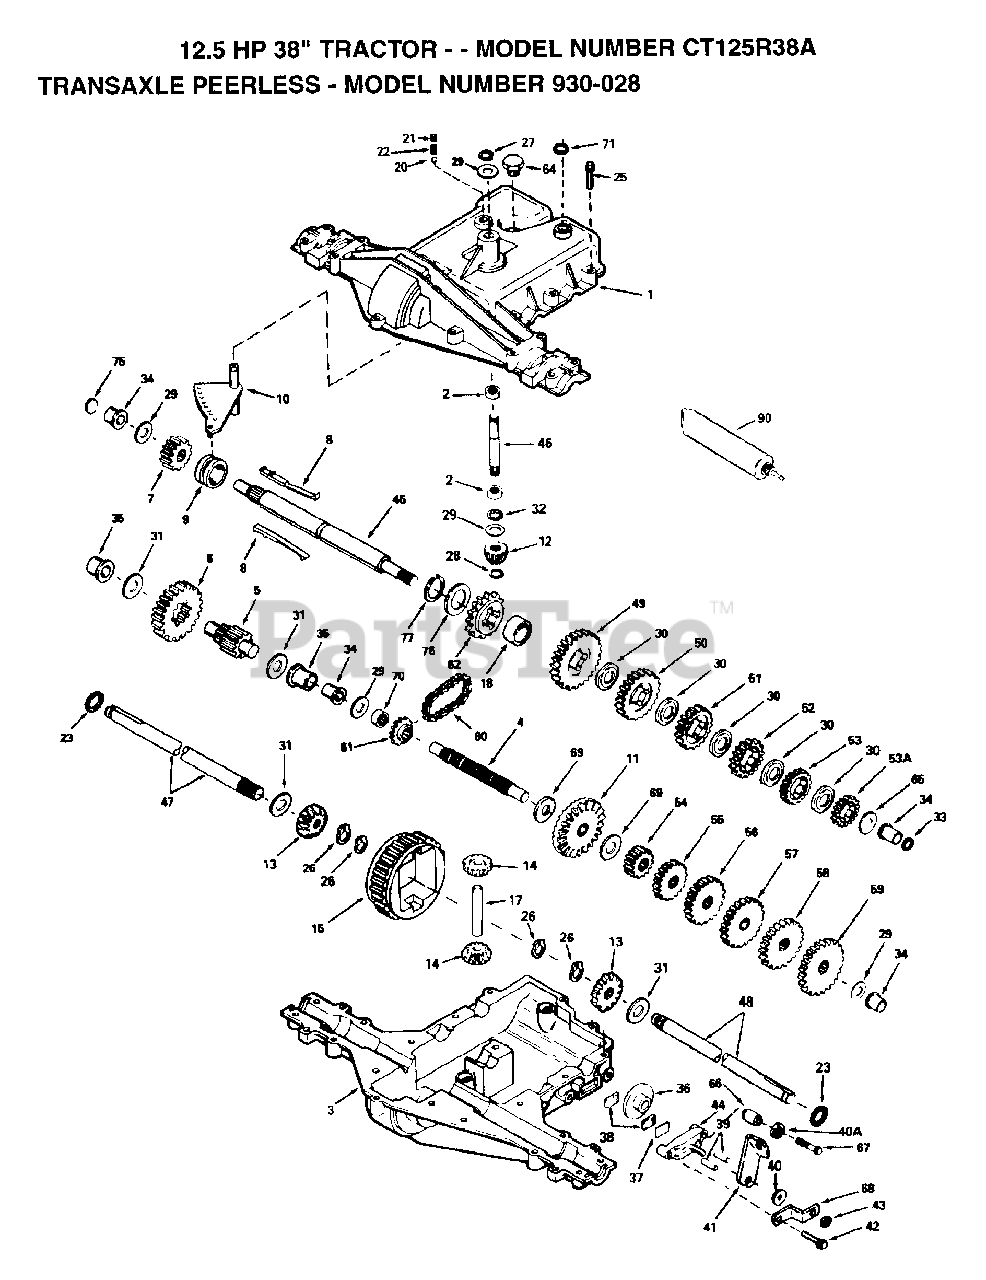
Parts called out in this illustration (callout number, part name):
1	COVER, TRANSAXLE
2	BEARING, NEEDLE
3	CASE, TRANSAXLE
4	SHAFT, COUNTER
5	SHAFT, PINION ASSEMBLY, OUTPUT
6	GEAR, OUTPUT
7	GEAR, SPUR, 15 TEETH
9	COLLAR, SHIFTER
10	ROD & FORK ASSY, SHIFT
11	GEAR, BEVEL, 42 TEETH
12	BEVEL PINION, INPUT
13	GEAR, BEVEL
14	GEAR, BEVEL, PINION
18	SPACER, NEUTRAL
20	BALL STEEL, 5/16" DIA.
21	SCREW, 3/8-16 X 3/8"
25	SCREW, 1/4-20 X 1-1/4
26	RING RETAINER
27	RING, RETAINER
28	RETAINING RING
29	WASHER THRUST
30	WASHER THRUST
33	SEAL, SQUARE CUT
34	BUSHING, FLANGED
35	BUSHING, FLANGED
36	DISK, BRAKE
37	PLATE BRAKE PAD
40	WASHER, FLAT
40A	WASHER FLAT
41	LEVER BRAKE
42	SCREW, 1/4-20 X 1-1/4
43	LOCKNUT 5/16-24
44	HOLDER BRAKE PAD
45	SHAFT, BRAKE, 4 KEYED
46	SHAFT, INPUT
49	GEAR, SPUR, 37 TEETH
50	GEAR, SPUR, 35 TEETH
51	GEAR, SPUR, 30 TEETH
52	GEAR, SPUR, 25 TEETH
53	GEAR, SPUR, 22 TEETH
53A	GEAR, SPUR, 19 TEETH
54	GEAR, SPUR, 12 TEETH
55	GEAR, SPUR, 15 TEETH
56	GEAR, SPUR, 20 TEETH
57	GEAR, SPUR, 25 TEETH
58	GEAR, SPUR, 28 TEETH
59	GEAR, SPUR, 31 TEETH
60	CHAIN, ROLLER
61	SPROCKET 9T
62	SPROCKET 18T (REV)
64	PLUG, THRDED, 9/16-18
65	WASHER, THRUST
67	SCREW FLNG HEX 1/4-20 X 2-1/4
68	BRKT BRAKE LEVER
69	WASHER THRUST
71	SEAL SQUARE CUT
76	WASHER, THRUST
77	RING, RETAINING
90	GREASE BENTONITE, 32 OZ.
